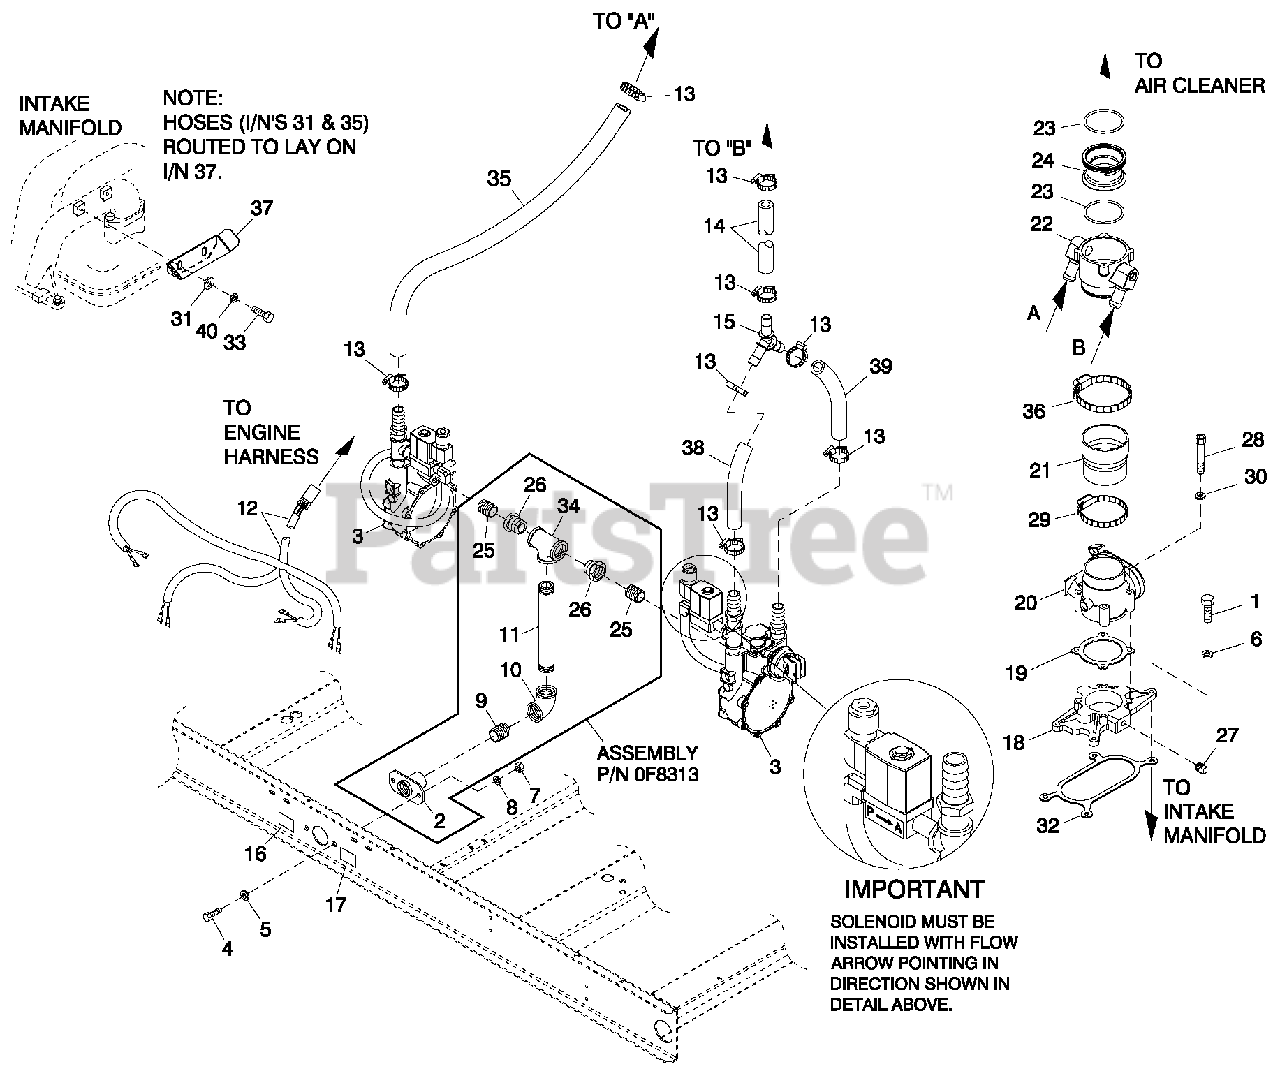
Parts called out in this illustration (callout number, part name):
1	SCREW HHC 5/16-18 X 1-1/4 G5
2	SUPPORT NAT GAS SOLENOID
3	REG ASSY 5.4L 80 KW NG CPL
4	SCREW HHC #12-1.75 X 20 G8.8
5	WASHER FLAT 1/2 ZINC
6	WASHER LOC K M8-5/16
7	NUT HEX M12-1.75 G8 YEL CHR
8	WASHER LOC K1/2
9	NIPPLE CLOSE 1.25 NPT X 1.625
10	ELBOW 90D1-1/4 NPT
11	NIPPLE PIPE 1-1/4 NPT X 3 (100 KW)
12	HARNESS, FUEL JUMPER DUAL REG (100 KW)
13	CLAMP HOSE #8.53-1.00
14	HOSE 3/4 ID SAE-30R2 (42" LG)
15	Y CONNECTOR 500 SERIES BARBS
16	DECAL INLET PRESSURE
17	DECAL FUEL INLET NG
18	ASSY,ADAPTER,THROTTLE BODY
19	GAS KET GOVERNOR ACTUATOR
20	ACTUATOR BOSCH 60 GOVERNOR
21	REDUCER 3.0" TO 2.75" TURBO
22	MIXER 40/60MM ACTUATOR ASSY
23	O-RING 2-3/4X3/32X2-15/16
24	VENTURI, THROTTLE 42MM (100 KW)
25	NIPPLE CLOSE 3/4X1.375
26	BSHGRDCR HEX1-1/4-3/4
27	PLUG STD PIPE 1/4 STEEL SQ HD
28	SCREW SHC M6-1.0X 50 C8.8
29	CLAMP HOSE #44 2.31-3.25
30	WASHER LOC K M6-1/4
31	WASHER FLAT M6
32	GAS KET ADAPTER THROT BODY
33	SCREW HHC M6-1.0X 20 G8.8
34	PIPE TEE 1-1/4 NPT
35	HOSE 3/4 ID SAE-30R2 (45" LG)
36	CLAMP HOSE #52 2.81-3.75
37	BRACKET, HOSE RISER
38	HOSE 3/4 ID SAE-30R2 (9.5" LG)
39	HOSE 3/4 ID SAE-30R2 (12" LG)
40	WASHER LOC K M6-1/4
